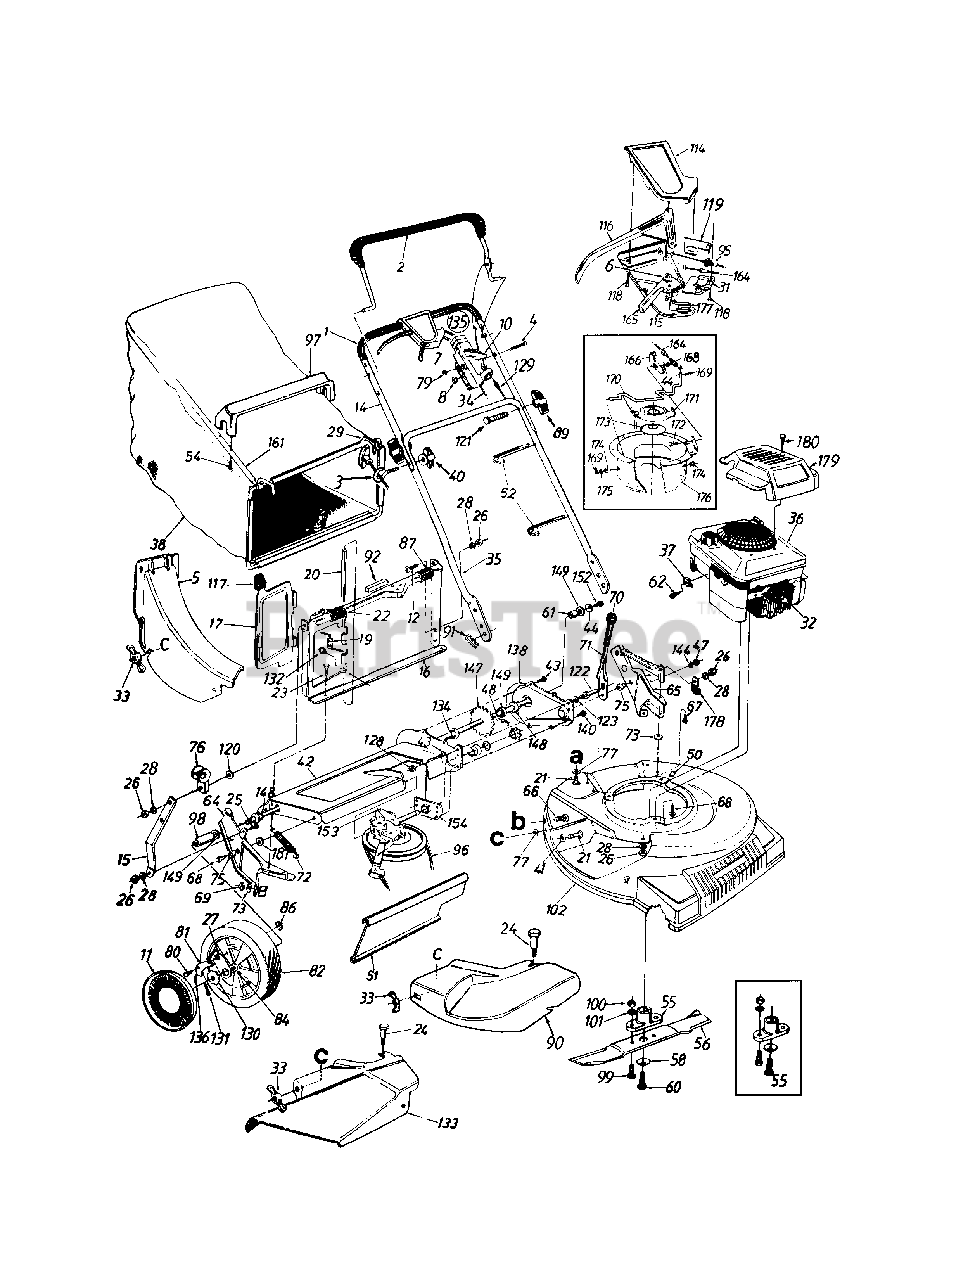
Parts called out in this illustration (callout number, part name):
2	Control Handle
3	Rope Guide
4	Oval C-Sunk Scr.
5	Rear Discharge Chute Ass'y.
6	3 Tooth Rack Gear Insert
7	Throttle Body
8	Spr. Wash. .66" I.D.
10	Throttle Lever
11	Hub Cap (Beige)
12	Truss Mach. Scr. 1/4-20 x .62"
19	Torsion Spring
20	Pivot Pin
21	Carriage Bolt 1/4-20 x .62"
22	Truss Mach. Scr. 1/4-20 x .75"
23	Hex AB-Tap Scr. 1/4-20 x .62" Lg.
24	Shoulder Bolt Special
25	Hex Bolt 1/4-20 x .62" Lg.
26	Hex Nut 1/4-20 Thd.
27	Pawl Plate
28	L-Wash. 1/4" I.D.
31	S.P. Control Cover
32	Spark Plug Insulator
33	Wing Nut
34	Throttle Cable 61"
36	Engine
37	Casing Clamp
38	Grass Bag
41	Fl-Wash. .344" I.D. x .62"
44	Bell-Wash. 1/4" I.D.
47	Hex Patch L-Nut 3/8-24 Thd.
48	#48 Chain .500" Pitch x 30 Links
51	Rear Flap
52	Cable Tie
54	Hex AB-Tap Scr. #12 x 1.25"
55	Blade Adapter Kit
56	21" Mulching Blade
58	Bell-Wash. .46" I.D.
60	Hex Bolt 7/16-20 x 1.5"
61	Spacer .513" I.D.
62	Hex Wash. Hd. Scr. #10-32 x .62" Lg.
64	R.H. Handle Wheel Brkt. Ass'y.
65	L.H. Handle Wheel Brkt. Ass'y.
66	Carriage Bolt 5/16-18 x .62"
67	Hex B-Tap Scr. 5/16-18
68	Hex TT-Tap Scr. 3/8-16
69	Hex Nut 5/16-18 Thd.
71	Height Adj. Lever
72	Extension Spring 3.80" Lg.
73	Bell-Wash. 5/16" I.D.
75	Shld. Spacer .5" Dia.
76	Rope Guide
77	Bolt Retainer 1/4 x .50" O.D.
79	Hex L-Nut 1/4-20 Thd.
80	Shld. Scr. .342" Dia. x .268
81	Pawl
82	Wheel Ass'y. Comp. (Beige)
84	Sleeve Bearing 1/2" I.D.
86	Flat Nut 1/4-20 Thd.
87	Panel Clip
89	Hand Knob
90	Mulching Plug
91	Hairpin Clip
95	S.P. Cable--50" Lg.
96	"V"-Belt
97	Bag Handle
98	Sleeve .526" I.D.
99	Hex Bolt 3/8-24 x 1.0" Lg.
100	Hex Nut 3/8-24 Thd.
101	L-Wash. 3/8" I.D.
115	Self-Propelled Control Cover
116	Control Lever
117	Door Grip
118	Fl-"C"-Sunk Hd. Tap Scr. #10 x .75" Lg.
119	6-Speed Rack Cable Brkt.
120	Fl-Wash. .285" I.D. x 1.25" O.D.
121	Curved Hd. Bolt 5/16-18 x 2" Lg.
122	Shld. Pin 1 .43" Lg.
123	L-Wash. 3/8" I.D.
128	Hex Jam Nut 3/8-24 Thd.
129	Control Cable--44"
130	Ratchet Wheel 1.62" O.D.
131	Cotter Pin 1/8" Dia. x 1"
132	Hex B-Tap Scr. #10 x .38" Lg.
133	Side Chute Deflector Ass'y.
134	Hex Flange Bearing
135	Throttle Box Comp.
136	Spring--Nylon
144	Fl-Wash. .385" I.D. x .87"
147	Rear Shaft Ass'y. 21.94" Lg.
148	Hex Flange Brg. .506" I.D.
149	Fl-Wash. .531" I.D. x .930"
152	Hex Bolt 1/4-20 x .62" Lg. (Grade 5)
153	Transmission Comp.
164	Spd. Control Cable--50" Lg.
165	6-Spd. Shift Lever
169	Cot-Pin 3/32" Dia. x .75" Lg.
170	Shift Rod
171	Movable Pulley Half Ass'y.
172	Carr. Bolt 1/4-20 x .5" Lg.
173	Splined Pulley Half
174	Flanged Bushing
175	Fl-Wash. .328" I.D. x .68" O.D.
176	Housing Ass'y.
177	Shift Lever Spring
179	Engine Cover (Black)
180	Screw #10 x 1.25" Lg.
181	Fl-Wash. .383" I.D. x 1" O.D.
